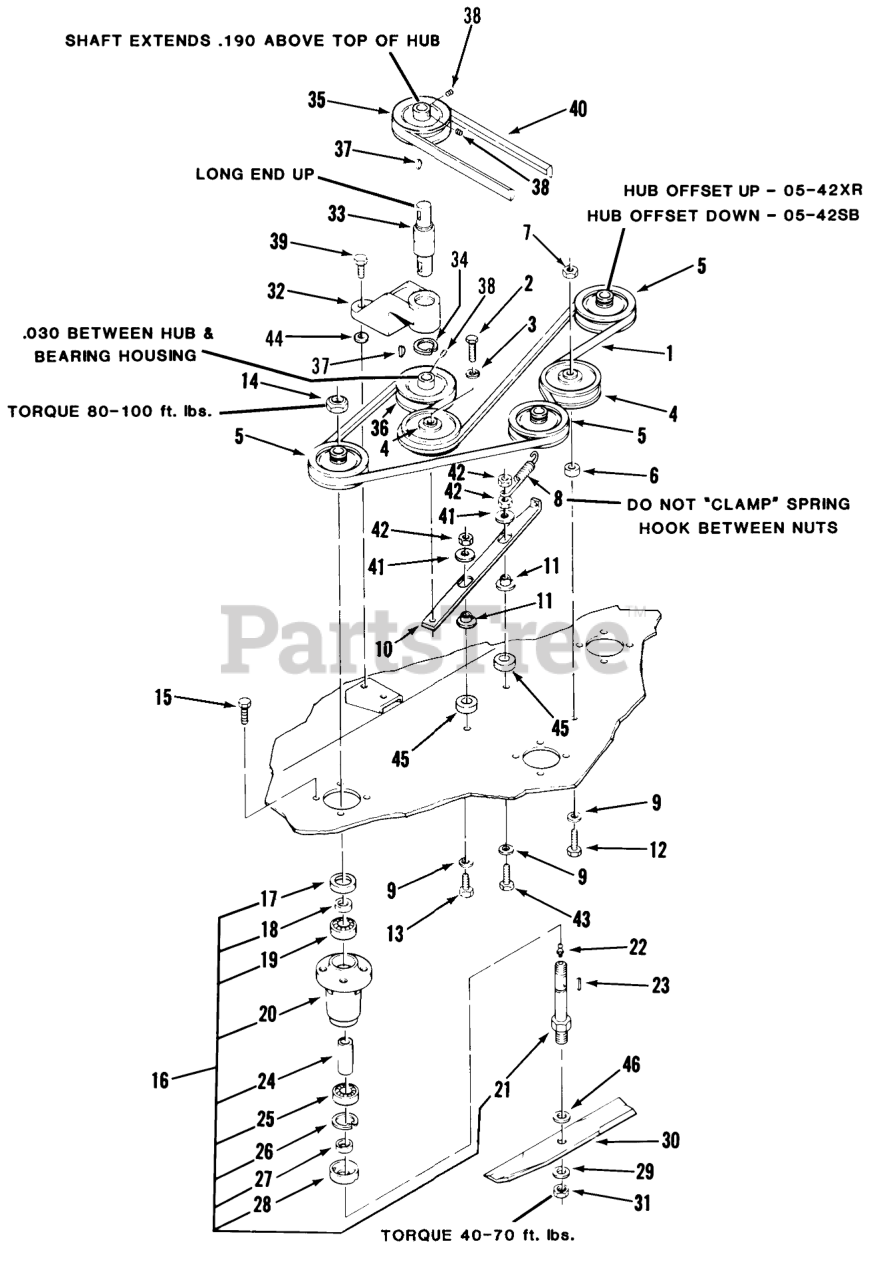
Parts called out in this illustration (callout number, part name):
1	V-BELT
2	BOLT HEX SPECIAL
3	LOCKWASHER
4	Idler Pulley
5	PULLEY-BLADE DRIVE
6	SPACER
7	Nut
8	SPRING-EXTENSION
9	WASHER
10	BAR-SLIDER
11	SPACER-BUSHING
12	Bolt
13	Bolt
14	Nut
15	Bolt
16	Spindle Assembly
18	SPACER-SEAL
19	BEARING-BALL
20	HOUSING-SPINDLE
21	7" X 3/4" SHAFT.JAK
22	Zerk
23	Hi-Pro Key 3/16 x 5/8
24	SPACER
25	BEARING-BALL
26	Ring-Snap
27	SPACER-BLADE
28	CUP-SPINDLE
29	SpeciaI Washer
30	BLADE KIT
31	Nut
32	HOUSING DRIVE BRG R
33	BEARING-INT SHAFT
34	Snap Ring
35	PULLEY
36	PULLEY-SPLIT
37	KEY-WOODRUFF
38	Set Screw
39	Bolt
40	V-BELT
41	WASHER
42	NUT
43	Bolt
44	WASHER
45	SPACER
46	Washer
